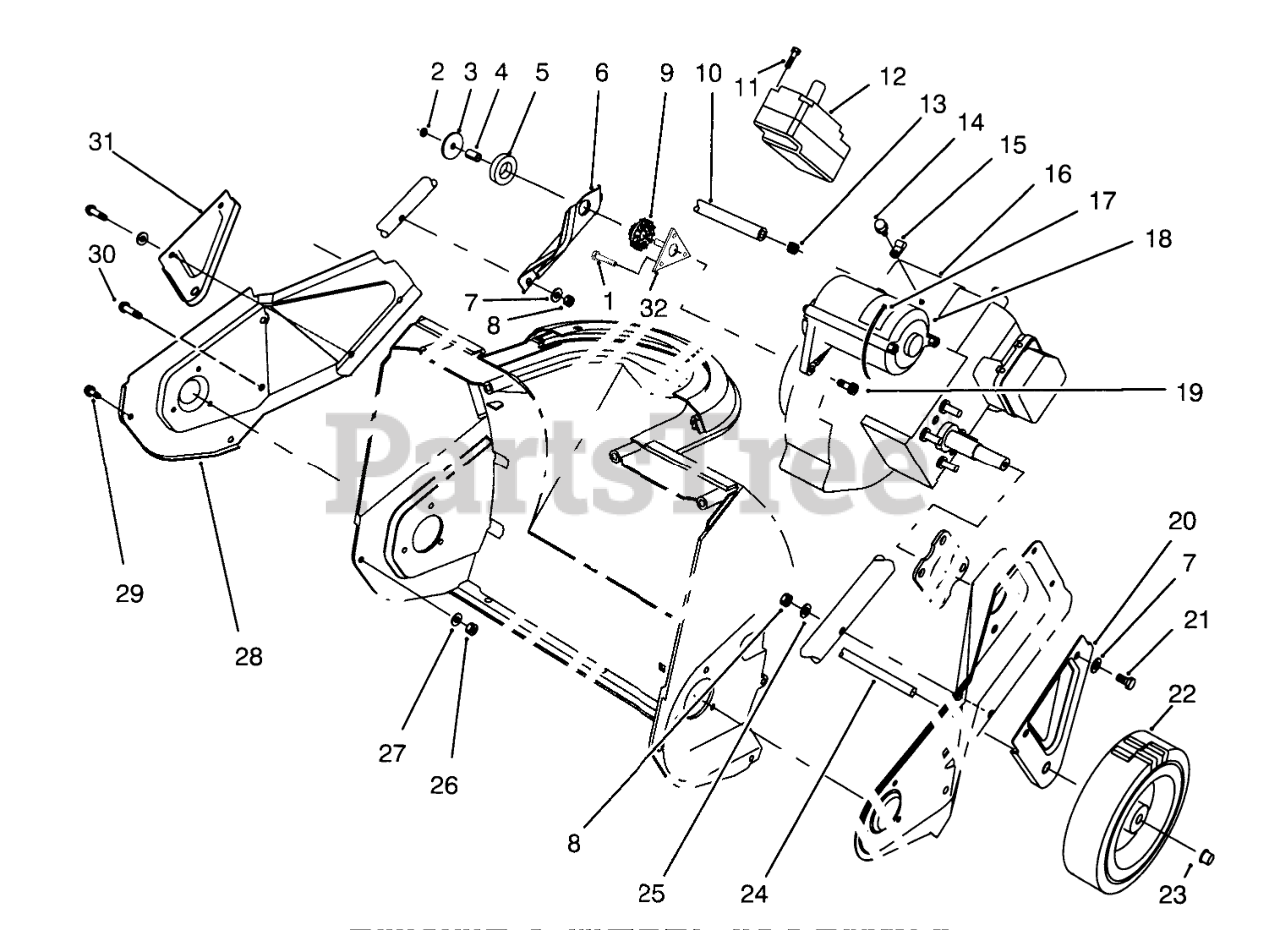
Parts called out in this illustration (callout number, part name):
1	SCREW X
2	NUT-LOCK, NI
3	WASHER-FLAT
4	SPACER-TUBULAR
5	Ring-Isolator
6	Support-Engine
7	WASHER-FLAT
8	NUT-LOCK, NI
9	BUSHING-ISOLATOR
10	LINE-GAS
11	SCREW-PLASTITE
12	ASM-Switch Housing
13	Clamp
14	SCREW-HWH
15	CLAMP
17	TIE-CABLE
18	Starter Motor Assembly
19	SCREW-HH, TORX
20	Bracket-Wheel
21	SCREW-HH
22	WHEEL
23	RETAINER-PUSH ON
25	WASHER
26	NUT-LOCK, NI
27	WASHER-FLAT
28	Sideplate-RH
30	SCREW-PLASTIC
31	Bracket-Wheel
32	BRACKET AND STUD ASM
